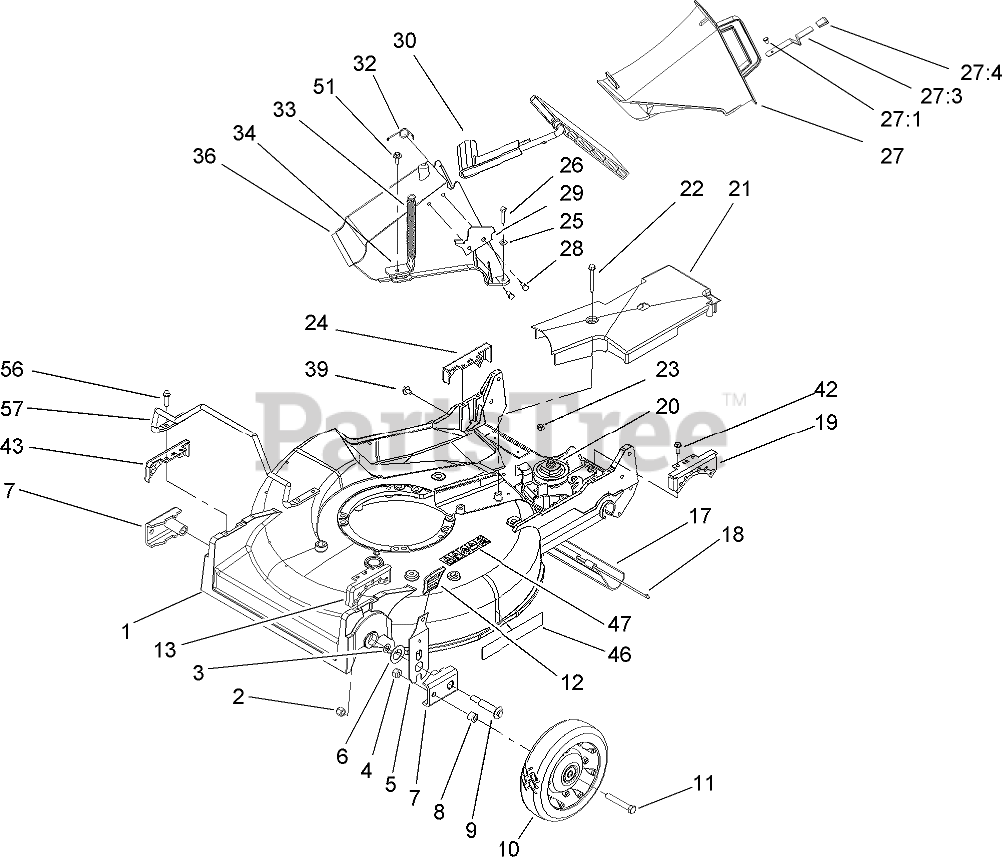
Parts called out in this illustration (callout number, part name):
1	HOUSING
2	NUT-LOCK
3	WASHER
4	NUT-LOCK, CONE
5	SPRING ARM ASM
6	WASHER-THRUST
7	ARM-PIVOT, FRONT
8	SPACER-WHEEL
9	BOLT-WHEEL
10	Wheel and Tire ASM
11	SCREW-HH
12	KNOB-HOC
13	QUADRANT-FRONT, LH
17	SHIELD-TRAILING
18	ROD-SHIELD
19	QUADRANT-REAR, LH
20	GEAR CASE ASM
21	COVER-BELT
22	SCREW-HHFTF
23	NUT-LOCK, NI
24	QUADRANT-REAR, RH
25	WASHER-FLAT
26	SCREW-HH
27	DISCHARGE PLUG ASM
27:1	RIVET-HEAD, FLAT
27:3	LATCH-PLUG, DISCHARGE
27:4	GRIP-LATCH
28	SCREW-PLASTITE
29	LATCH-PLATE
30	DISCHARGE DOOR ASM
32	RETAINER-DOOR
33	SPRING-DOOR
34	BRACKET-SPRING
36	TUNNEL-DISCHARGE
39	SCREW AND WASHER ASM
42	SCREW-HWHTF
43	QUADRANT-FRONT, RH
47	DECAL-DANGER
51	SCREW-HWH
56	SCREW-HWHTF
57	GUARD-ENGINE
